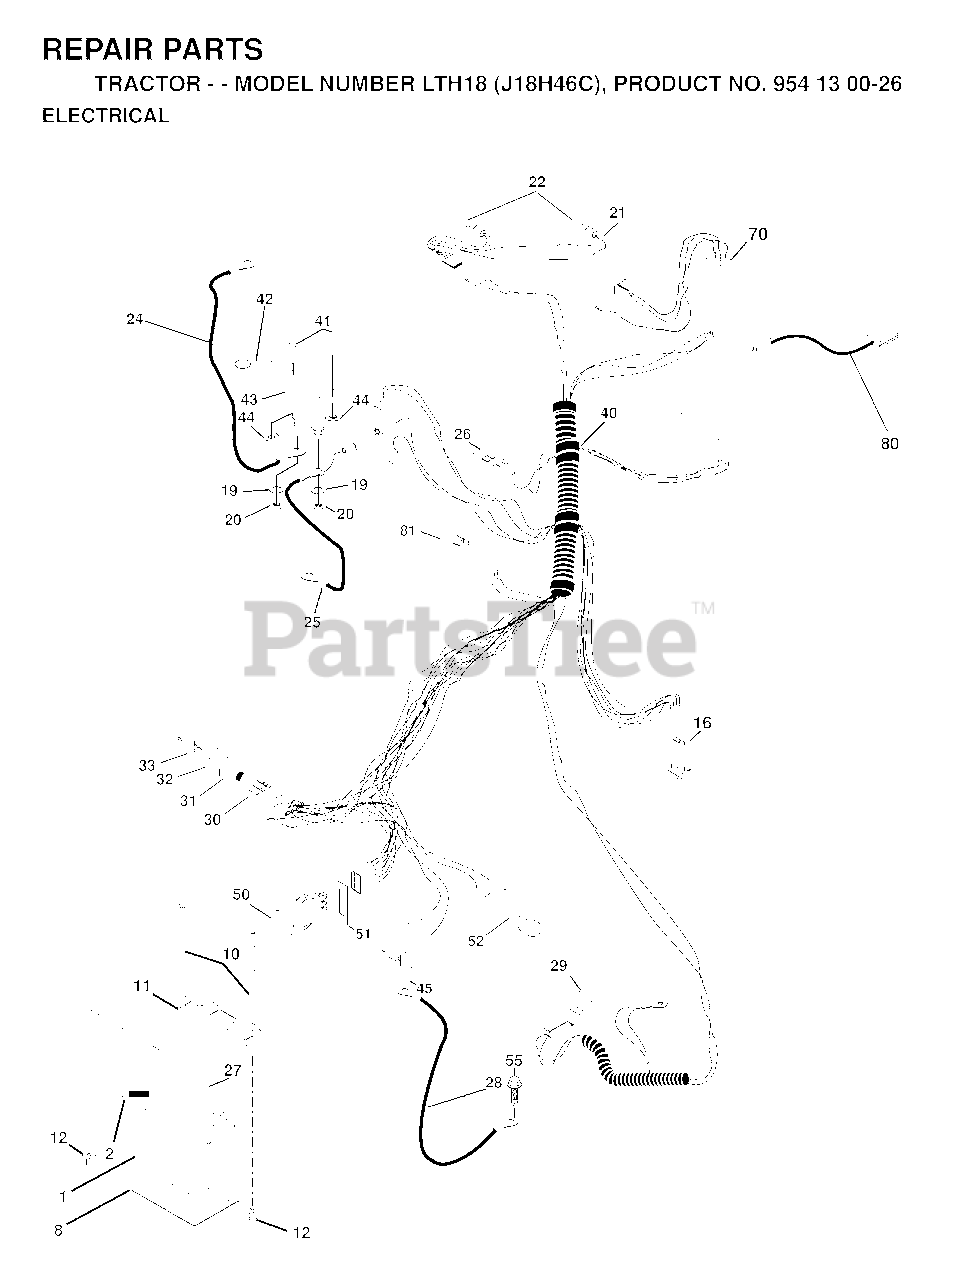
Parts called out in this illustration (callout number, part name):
1	REPL BY 532 12 38-99
8	BATTERY TRAY T
10	BOLT 1/4-20 X 7.5
11	BATTERY HOLDDOWN
12	NUT, PUSH NYLON 1/4" BATTERY
16	SWITCH INTERLOCK
19	LOCKWASHER
20	NUT
21	HARNESS ASM HDLIG
22	LIGHTBULB
24	BATTERY CABLE GT
25	CABLE BATTERY 6 GA 22" W/16W
27	NUT
28	CABLE GROUND 6 GA 21" 90T BLK
29	PLUNGER SWITCH (COLOR:OLIVE)
30	SWITCH.IGNITION.4.POSITION
31	NUT IGNITION
32	COVER SWITCH KEY
40	HARNESS.IGNITION
42	TERMINAL COVER
43	SOLINOID
50	SWITCH PTO 3 PDT
51	RETAINING RING
52	WIRE PROTECTION LOOP
80	HARNESS, CLUTCH
81	RELAY.ASSY.T
